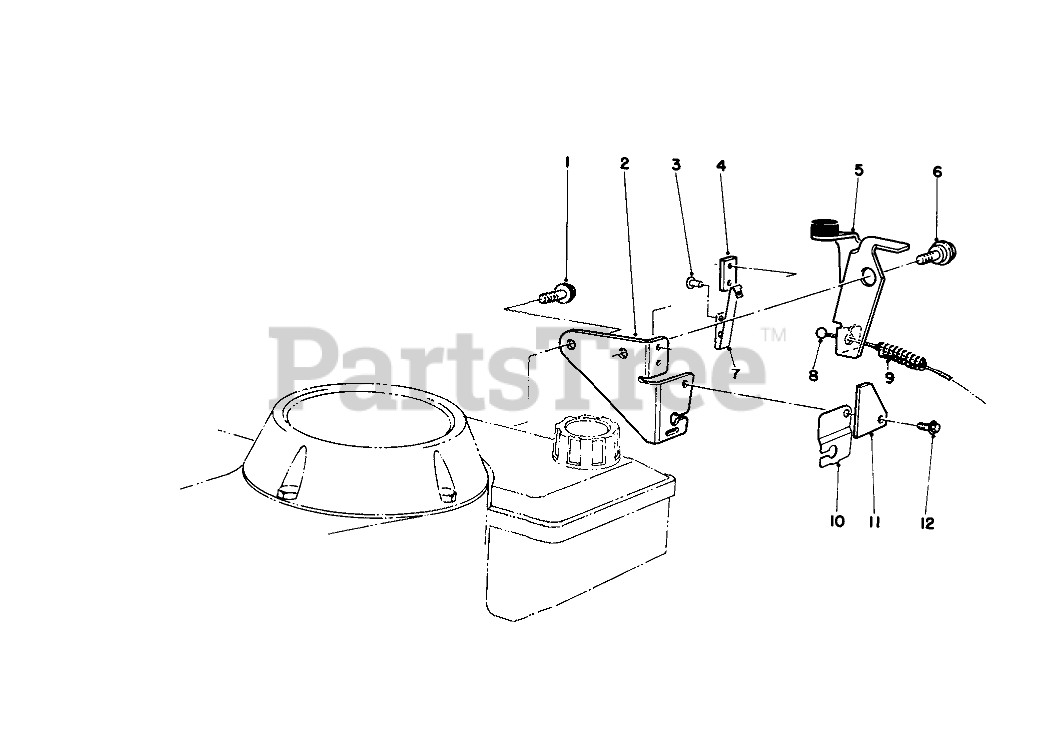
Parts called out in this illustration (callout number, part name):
1	THO FORM SCREW M6 X 1
2	Plate-Mounting Assembly (Incl. Ref. #3, 4 & 7)
3	RIVET-PLASTIC
4	Strap-Insulation
5	BRAKE PLATE ASM
6	Screw-Shoulder
7	STRAP-GROUND
8	BRAKE CABLE
9	SPRING-COMPRESSION
10	CABLE CLAMP
11	STOP-GROUND STRAP
12	SCREW
